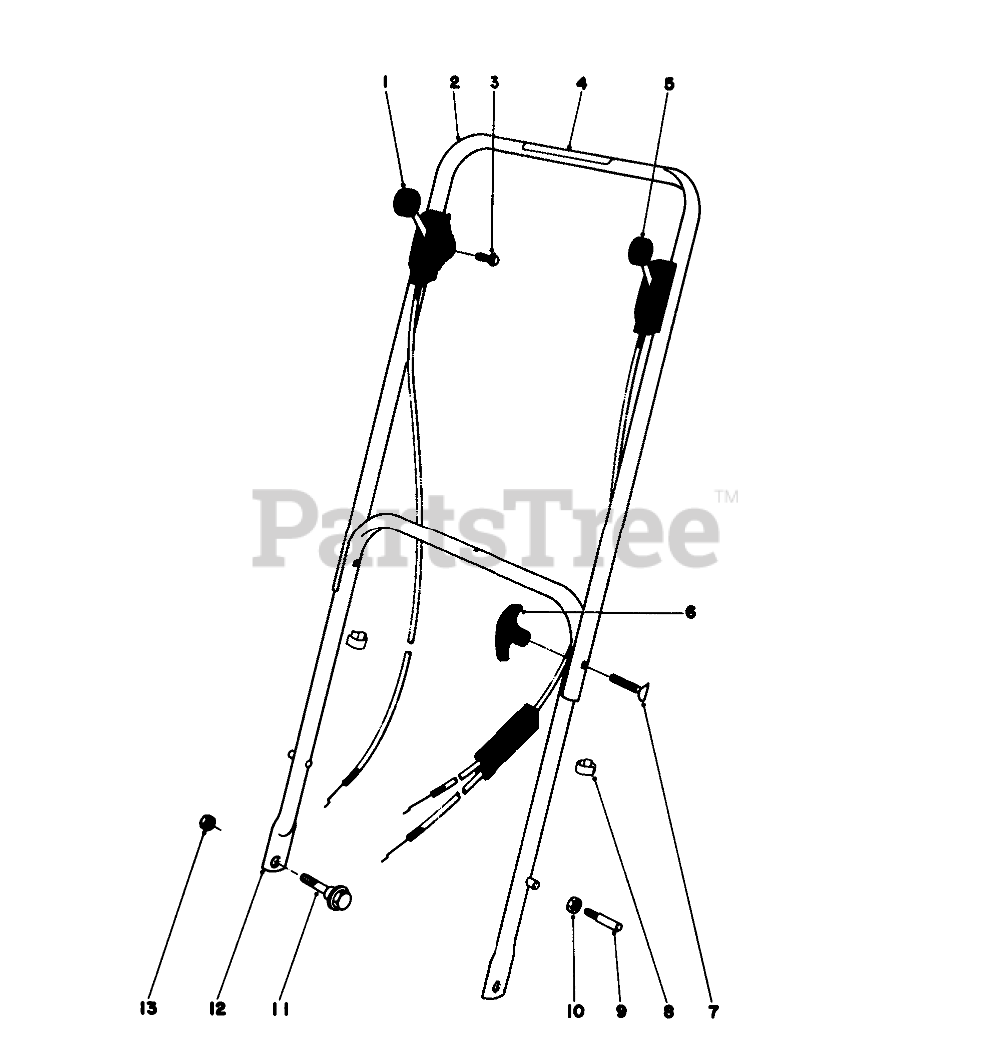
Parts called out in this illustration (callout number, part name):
1	Throttle Control
2	UPPER HANDLE
4	Decal
5	Traction Control
6	Handle Knob
7	HANDLE SCREW
9	HANDLE PIN
10	Nut
11	SCREW-SHOULDER
12	Lower Handle
13	Nut
